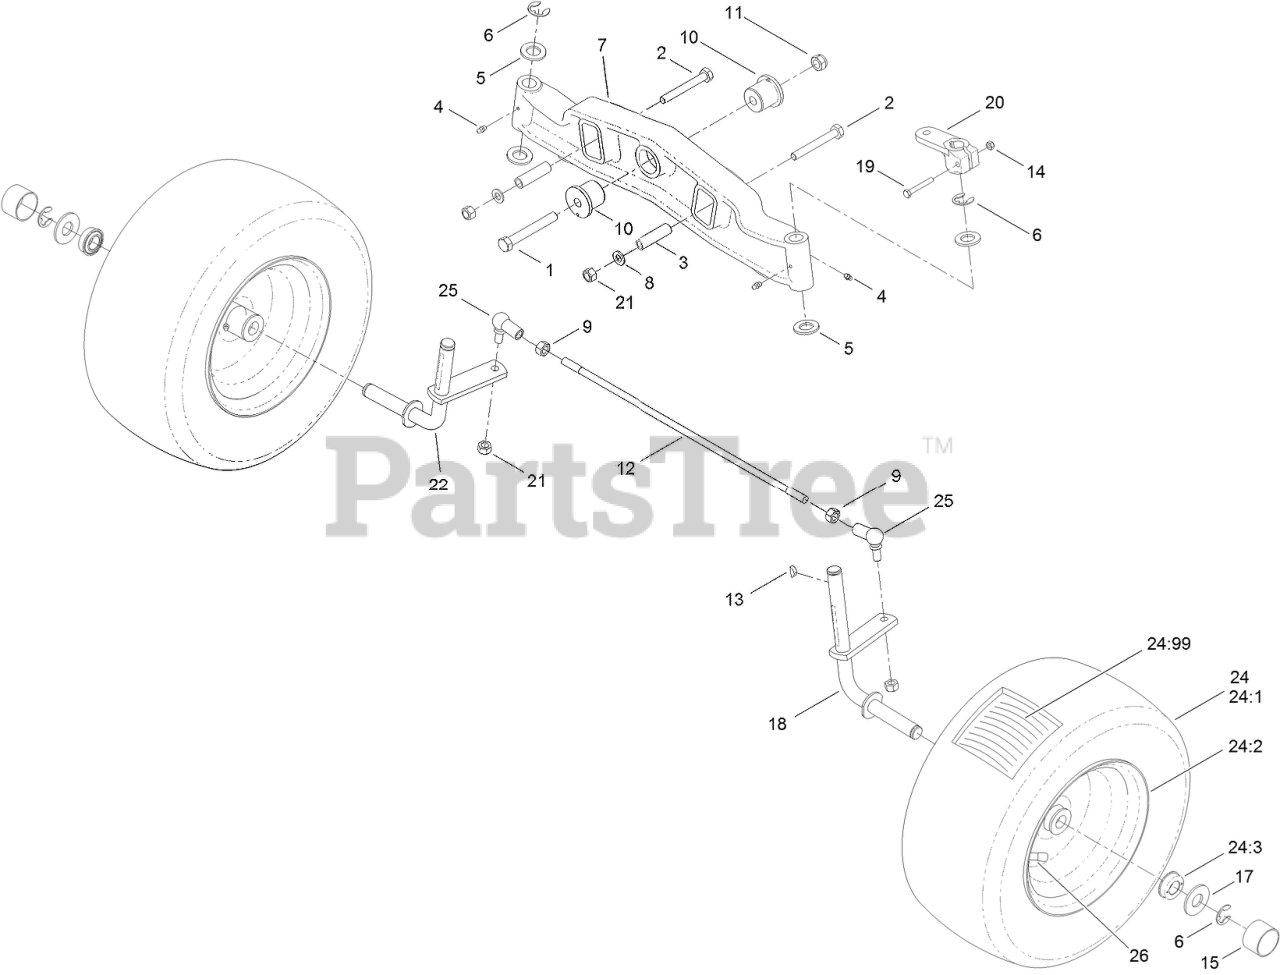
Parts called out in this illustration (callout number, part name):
1	SCREW-HH
2	SCREW-HH
3	SPACER
4	FITTING-GREASE
5	WASHER-FLAT
6	CLIP-SPRING
7	AXLE-FRONT
8	WASHER-FLAT
9	NUT
10	BUSHING-AXLE, FRONT
11	NUT-LOCKING, SELF
12	ROD-TIE, FRONT AXLE
13	KEY-WOODRUFF
14	NUT-LOCK
15	CAP-HUB
17	WASHER
18	SPINDLE-FRONT, LEFT
19	SCREW-HH
20	LEVER-SPINDLE, STEERING
21	NUT-LOCK, NI
22	SPINDLE-FRONT, RIGHT
24	WHEEL ASM
24:2	RIM-FRONT
24:3	BEARING-WHEEL
24:99	TUBE-INNER
25	JOINT-BALL, ANGLE
26	Valve-Tire
